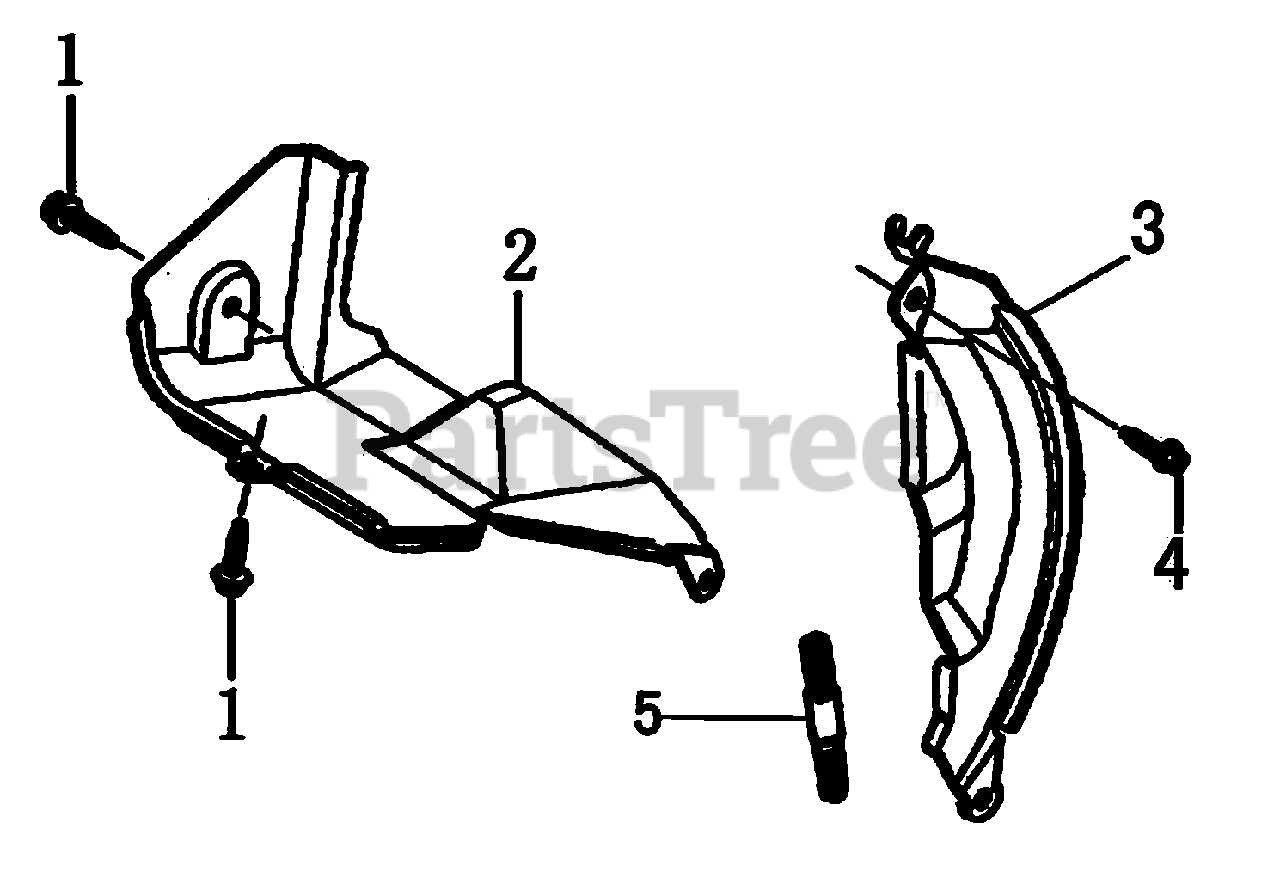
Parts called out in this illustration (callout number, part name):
1	BOLT, FLANGE 6X8
2	SHROUD COMP
3	PLATE, SIDE
4	BOLT, FLANGE 6X20
5	BOLT, STUD
